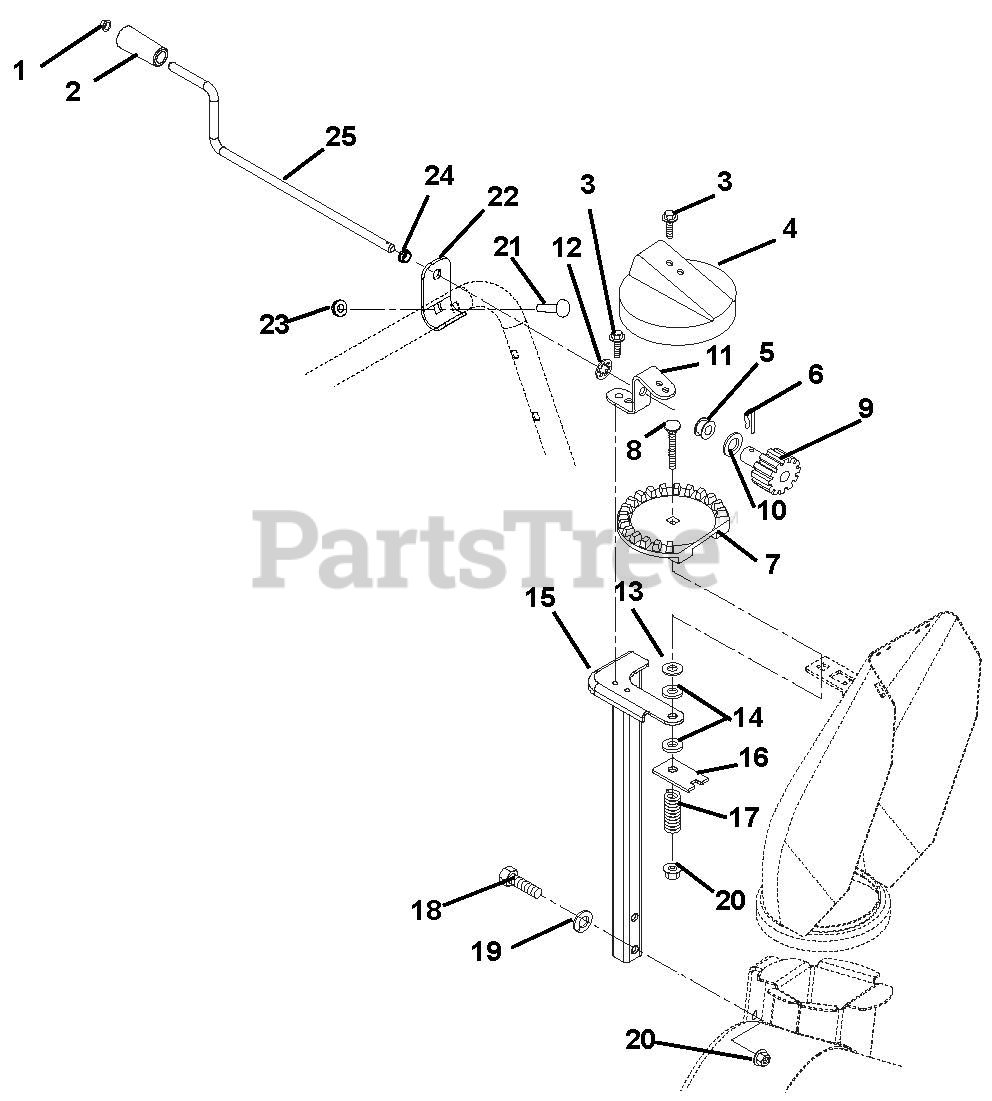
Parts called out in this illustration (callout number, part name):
1	CAP, 3/8 ROD YWZC
2	KNOB, CHUTE CRANK
3	@SCR-TAP .25-20X.50 HWH TR YWZ
4	GEAR COVER
5	BUSHING, POLYLINER-.63 SNAPIN
6	PIN, SPRING CLIP
7	CHUTE GEAR
8	@BLT-RDHDSQNK .38-16X2.50 G5YZ
9	PINION GEAR W/BRACKET
10	WSHR-THRST .625 X 1.0 X .03
11	BRACKET, PINION GEAR
12	PUSHNUT .625
13	WSHR-FL-STL .380X1.50X.062 YWZ
14	FRICTION WASHER
15	WELDMENT, CHUTE PEDESTAL
16	PLATE, FRICTION
17	SG-COMP .187X.56X1.62
18	@BLT-HEX .38-16X1.75 GR5 YWZC
19	@WSHR-LK .38X.094 REG YWZC
20	@NUT-LK-TOP-FLG .38-16 YWZC
21	@BLT-RDHDSQNK .31-18X1.50 G5YZ
22	BRACKET, CRANK SUPPORT
23	@NUT-LK-TOP-FLG .31-18 YWZC
24	BUSHING, POLYLINER-.38 SNAPIN
25	ROD, CHUTE CRANK
